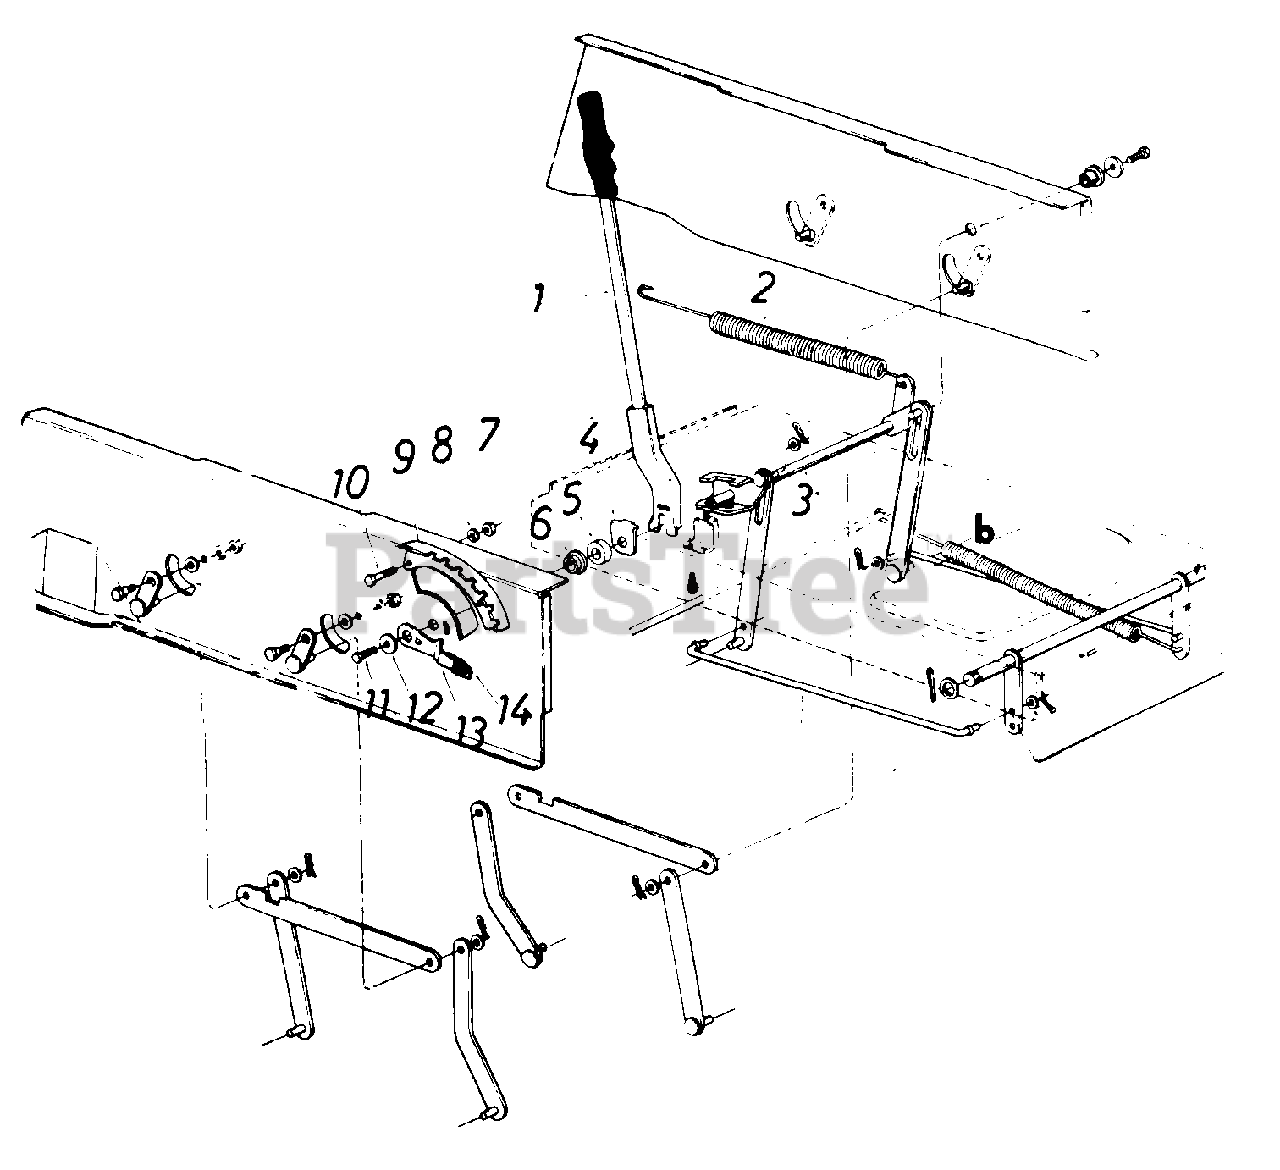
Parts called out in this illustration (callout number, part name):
1	Lift Handle Ass'y.
2	Extension Spring .99" O.D. x 11" Lg.
5	Rubber Wash. 1.50" O.D. x .63" I.D.
6	Flange Wash. .628" I.D. x 1.25" O.D.
7	Hex Nut 5/16-18 Thd.
8	L.-Wash. 5/16" I.D
9	Index Bracket
10	Hex Bolt 5/16-18 x .75" Lg.
11	Hex Wash. Hd. Self-Tap Scr. 5/16-18 x .62" Lg.
12	Fl.-Wash. .344" I.D. x 1.25" Lg.
13	Deck Lift Down Stop
14	Knob
